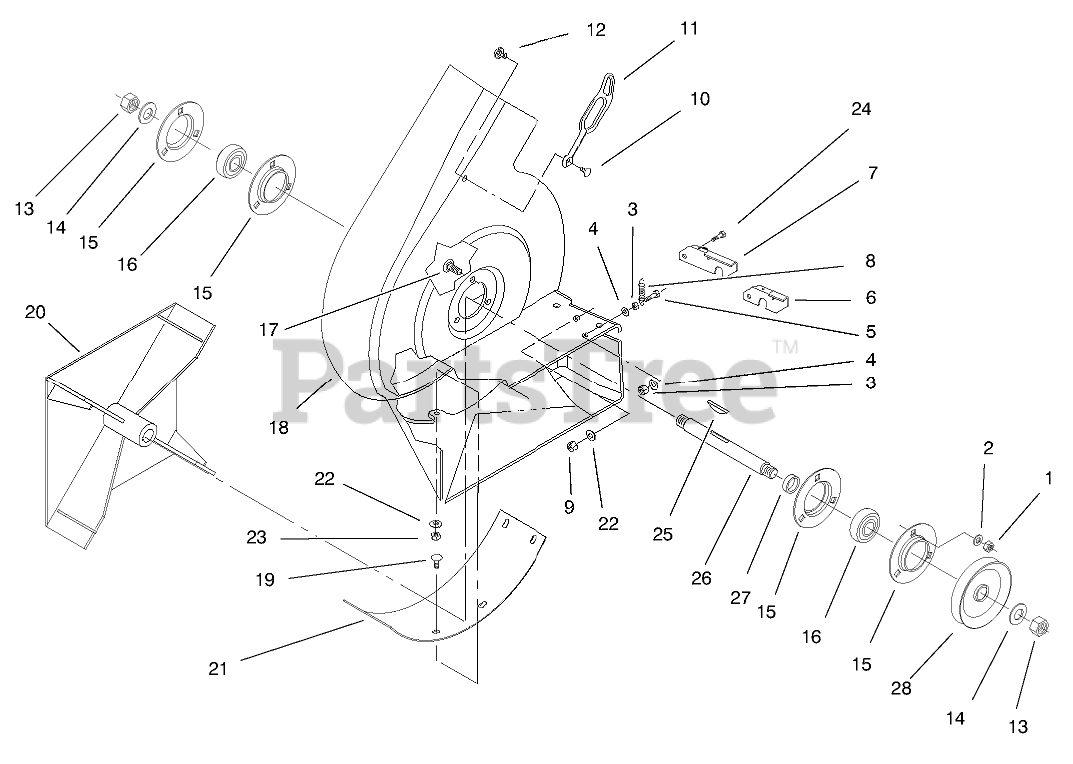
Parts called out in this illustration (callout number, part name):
1	NUT-HEX
2	WASHER-LOCK
3	NUT-HEX
4	WASHER-FLAT
5	SCREW-HWH
6	42" BLOWER LATCH B
7	48" BLOWER LATCH B
8	SPRING-EXTENSION
9	NUT-LOCK, NI
10	FASTENER-PANEL
11	RETAINER-DUCT
12	SPACER-INTERLOCK
13	NUT-JAM
14	WASHER-LOCK
15	FLANGE
16	BEARING-BALL
17	SCREW-CARR
18	HOUSING-VAC, BLOWER
19	SCREW-CARRIAGE
20	Impeller
21	COVER-BLOWER, BOTTOM
22	WASHER-FLAT
23	NUT-LOCK, NI
24	SCREW-HH
26	SHAFT-BLOWER
27	Spacer
28	PULLEY-BLOWER
